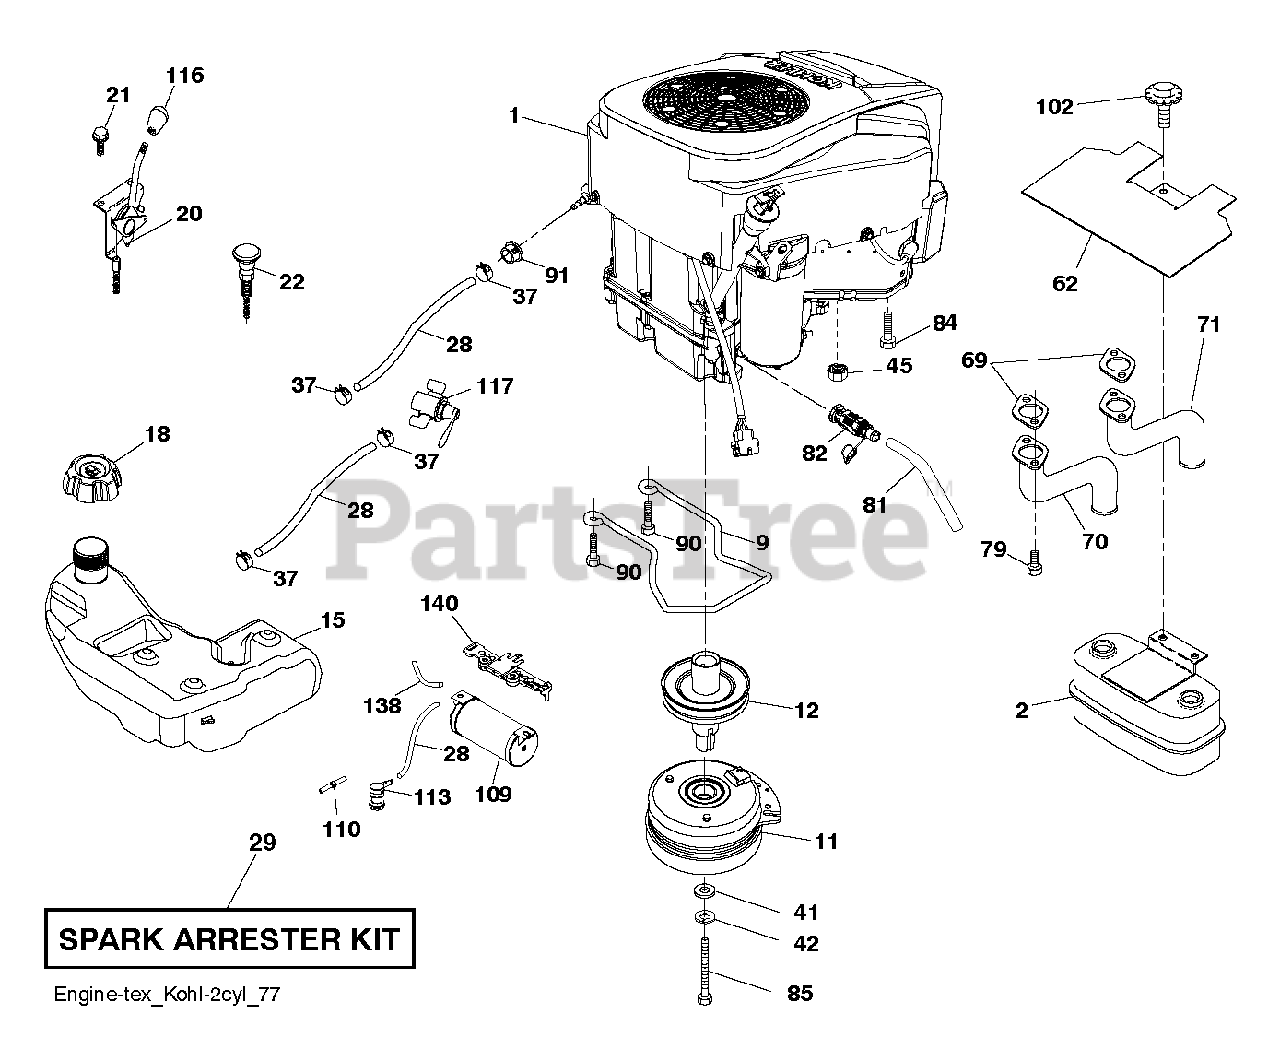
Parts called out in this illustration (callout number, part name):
2	Muffler Assembly, Twin MN
9	KEEPER.BELT.ENG.4.25"2.BLT.431
11	CLUTCH. 5.0 PD. 2.5 OFFSET
12	PULLEY.EXTENDED.SHAFT.GROUND
15	TANK.ASM.FUEL.4R.GAL.CARB.17
18	CAP ASSY FUEL 3" GRAY
20	THROTTLE.KOHL.PRO.#88PAD_46"
21	SCREW.#10 X 0.750.BOS
22	CONTROL.CHOKE.ERGO.PUSH-IN.BLA
28	Fuel Hose, 1/4" Low Perm
29	KIT.SPARK ARRESTOR 794945 B&S
37	HOSE CLAMP
42	WASHER 7/16 LOCK
45	NUT
62	SHIELD.HEAT.MUFFLER
69	GASKET.EXHAUST.KOHL.CV18-CV26
70	PIPE.EXHAUST.LH.CV18/20
71	PIPE.EXHAUST.RH.CV18/20
79	SCREW.SOCKET HD.5/16-1
81	TUBE, DRAIN OIL ASM.
82	VALUE.OIL.DRAIN
84	SCREW 3/8-16X1
85	BOLT.HEX.7/16-20X5.GR5.GREEN
90	SCREW 3/8-16X1
91	BUSHING.1.375OD
102	SCREW
109	CANISTER CARB, FLEX TECH, 6.3
110	VALVE.ASM.ANTI-SLOSH
113	VALVE.SLANT.CARTRDG.90 DEG.TEX
116	KNOB - SHIFT
117	VALVE FUEL RESERVE
138	RP PURGE LINE
140	BRACKET BRACKET, CARBON CAN, F
